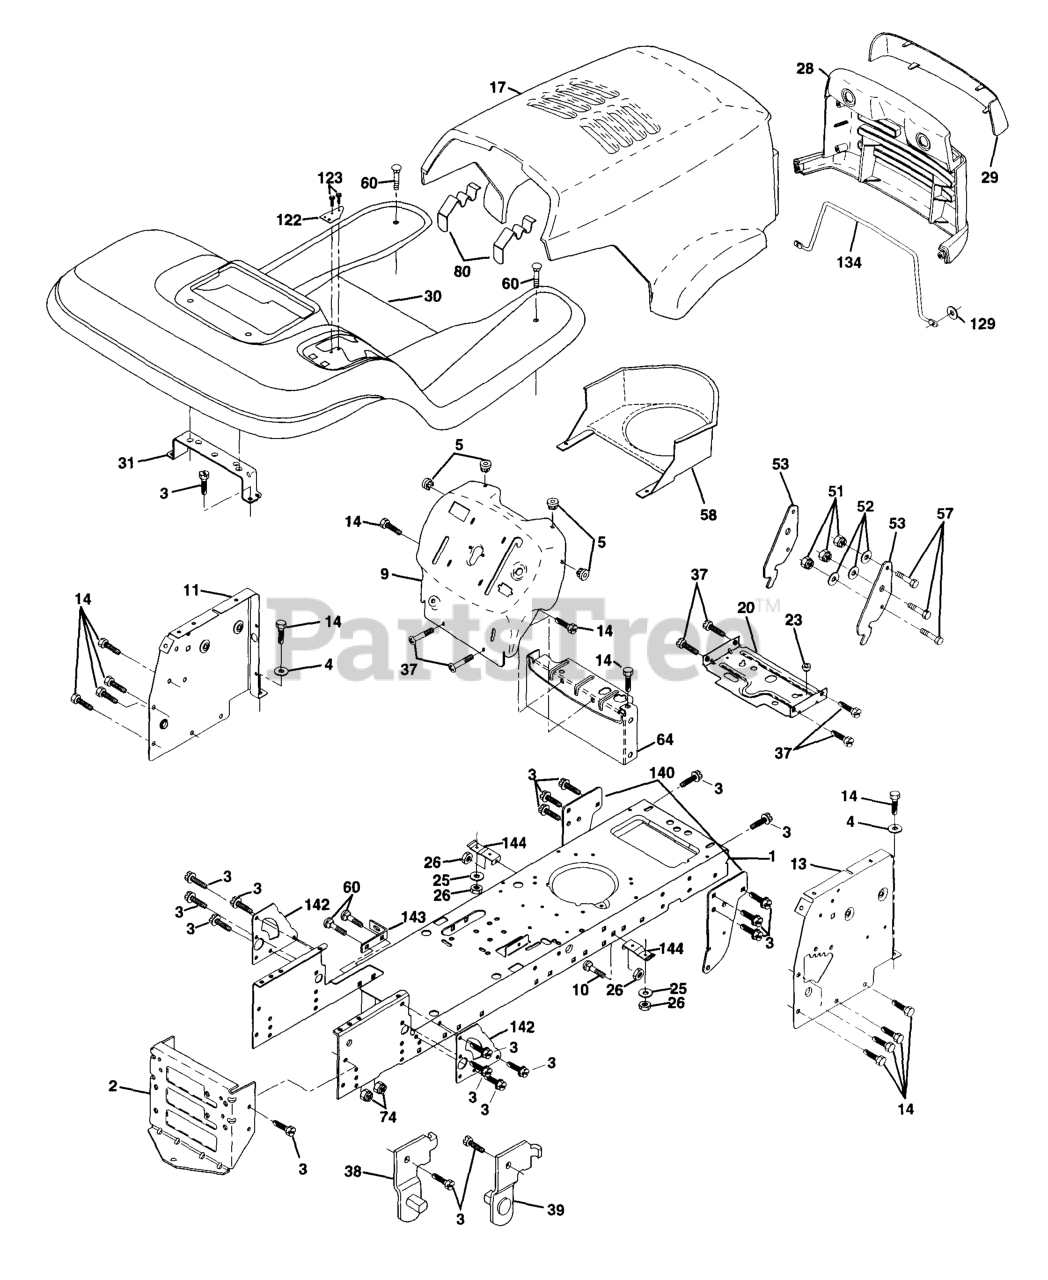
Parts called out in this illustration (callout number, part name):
1	CHASSIS WELDMENT
2	STRETCH DRAWBAR
3	SCREW
4	Washer 13/32 x 3/4 x 16 Ga.
5	BUMPER.RUBBER.HOOD
9	DASH P/L GREY LTH-120
10	BOLT D
11	PANEL DASH LH
13	PANEL DASH RH
14	SCREW LT
17	HOOD - LT/YT
20	PLATE MTG
23	BUSHING.SNAP.NYL.BLK.
25	WASHER
26	NUT
28	GRILLE LT/PL HUSQVARNA
29	LENS LT/PL HUSQVARNA
30	FENDER FOOTREST
31	BRACKET.SUPPORT.FENDER
37	Screw Thdrol 6/16-18 x 1/2 TYT
38	BRACKET LH PIVOT
39	BRACKET RH PIVOT
51	LOCKNUT.NYLOC.1/4-20
52	WASHER
53	BRACKET PNT PICK OFF LT/PL
57	BOLT
58	AIR DUCT P/L/LT
60	Bolt Rdhd Sqnk 3/8-16unc x 3/4
64	DASH LOWER
80	LATCH HOOD
129	WASHER
134	ROD SUPPORT HOOD LT/PL HUSQ
140	BRACKET CHASSIS FRONT
142	PLATE REINFORCEMENT
143	BRACKET, SWAY BAR
144	BRACKET FOOTREST
146	SCREW TORX HD 5/16X18
